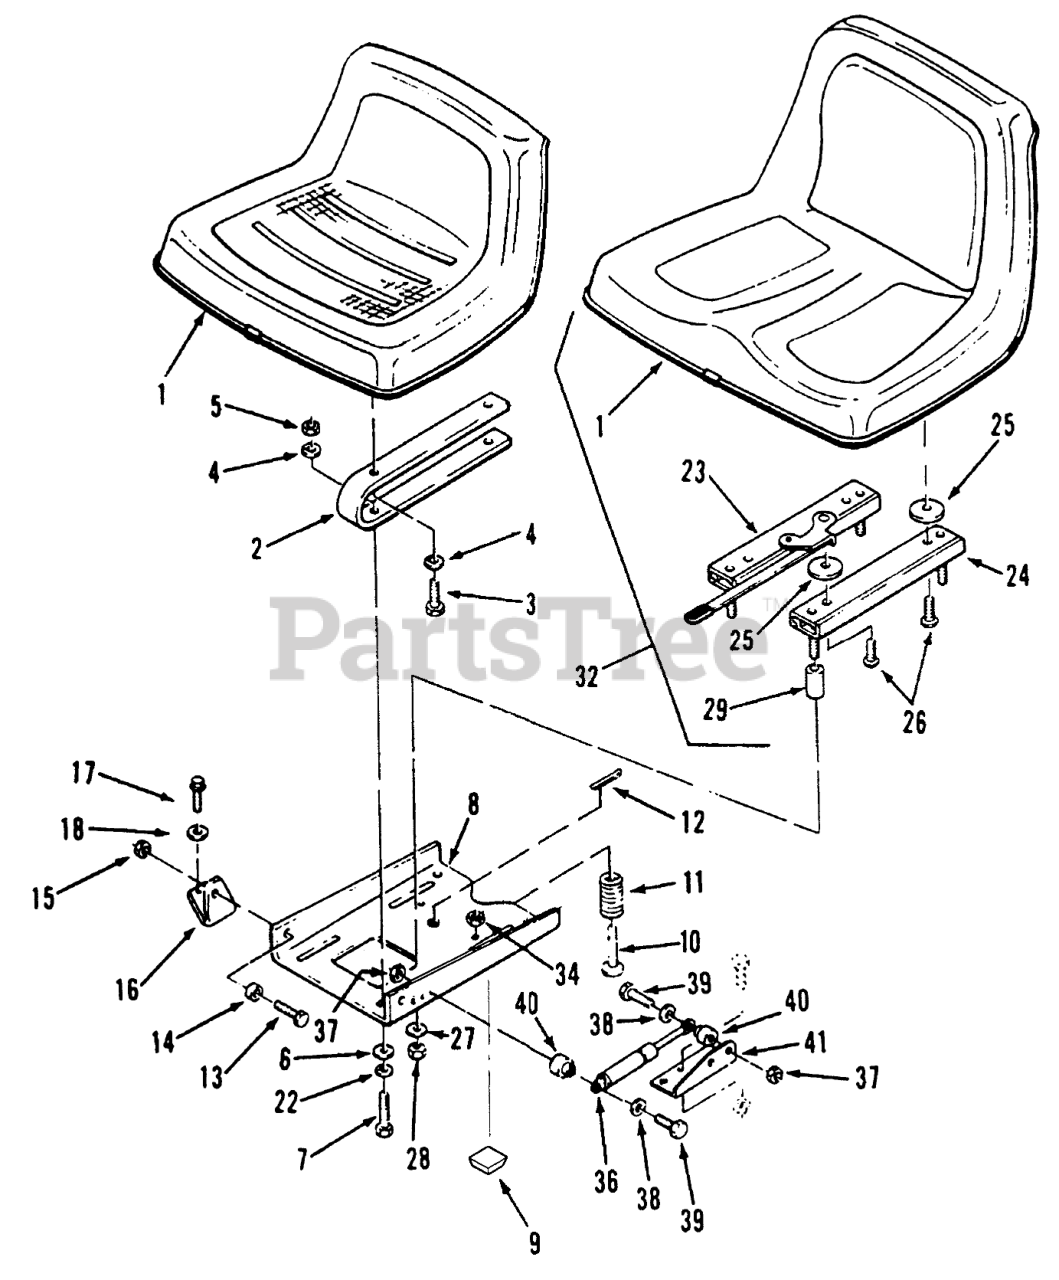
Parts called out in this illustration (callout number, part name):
1	Seat (Used on 312-H & 416-H)
2	Seat Spring
3	SCREW-HH
4	WASHER-LOCK
5	NUT-LOCK, NI
6	WASHER-PLAIN
7	SCREW-HH
8	Plate-SeatPivot
9	BUMPER SJ5514 BLACK
11	SPRING-SEAT SWITCH
12	PIN-COTTER
13	SCREW-HH
14	BUSHING
15	NUT-LOCK, NI
16	Bracket-Pivot RH
17	Bolt
18	WASHER-PLAIN
22	WASHER-LOCK
23	Adjuster-Seat
24	ADJUSTER-R.H. SEAT
25	SPACER-NYLON
26	Screw
27	WASHER-FLAT
28	NUT-HEX
29	SPACER
32	Seat Assy-Deluxe (Includes Items 1, 23, 24, 25, 26 & 29)
34	NUT-LOCK, NI
36	GAS SPRING
37	NUT-LOCK, NI
38	WASHER-FLAT
39	SCREW-HH
40	SPACER
41	BRACKET-CYLINDER R
